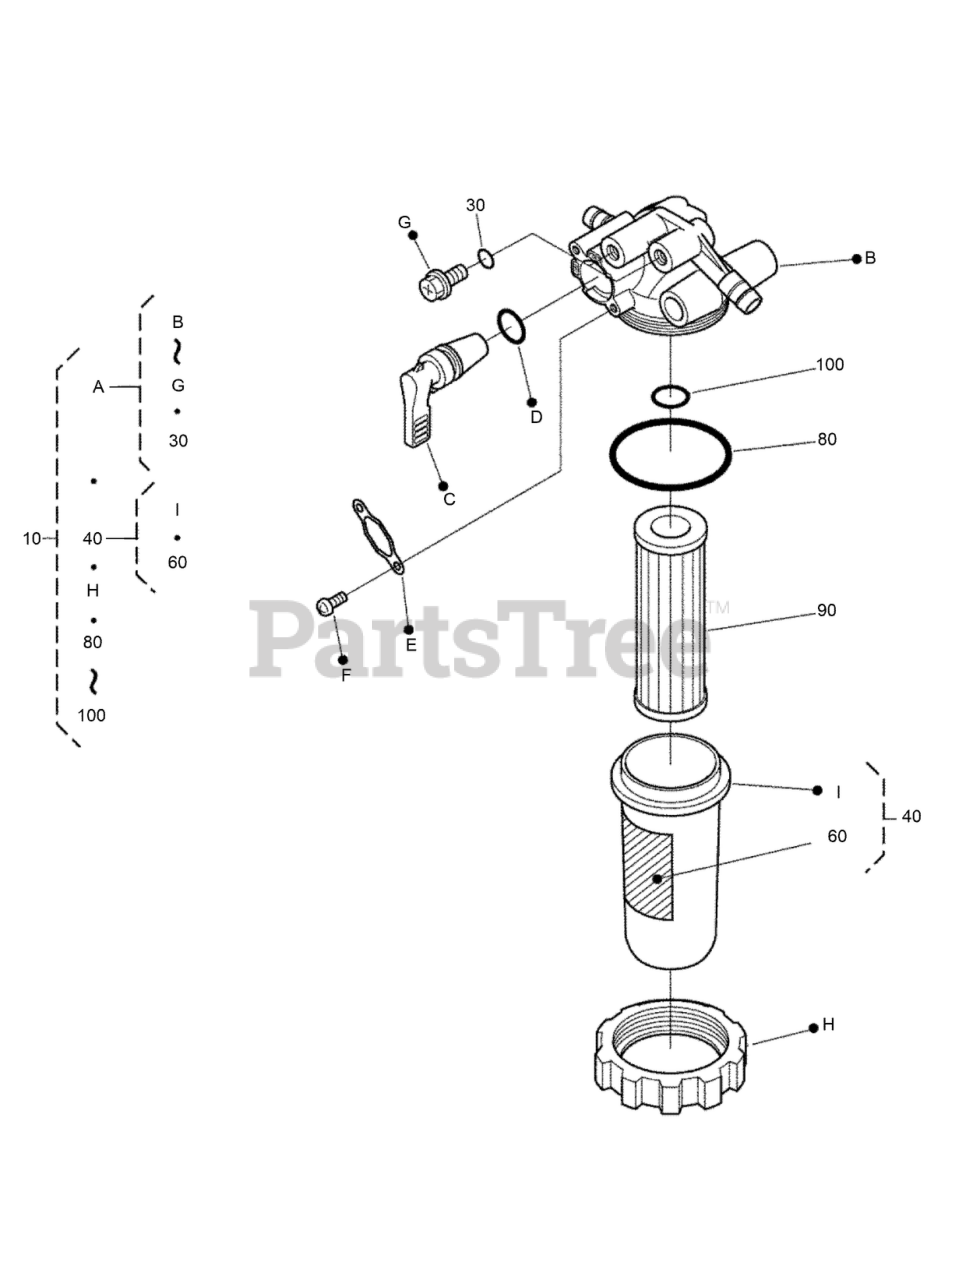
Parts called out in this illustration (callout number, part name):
10	FILTER,ASSY(FUEL)
30	O RING
40	ASSY CUP,FILTER
60	LABEL,FUEL
80	O-RING
90	FILTER, GASOLINE
100	O-RING
